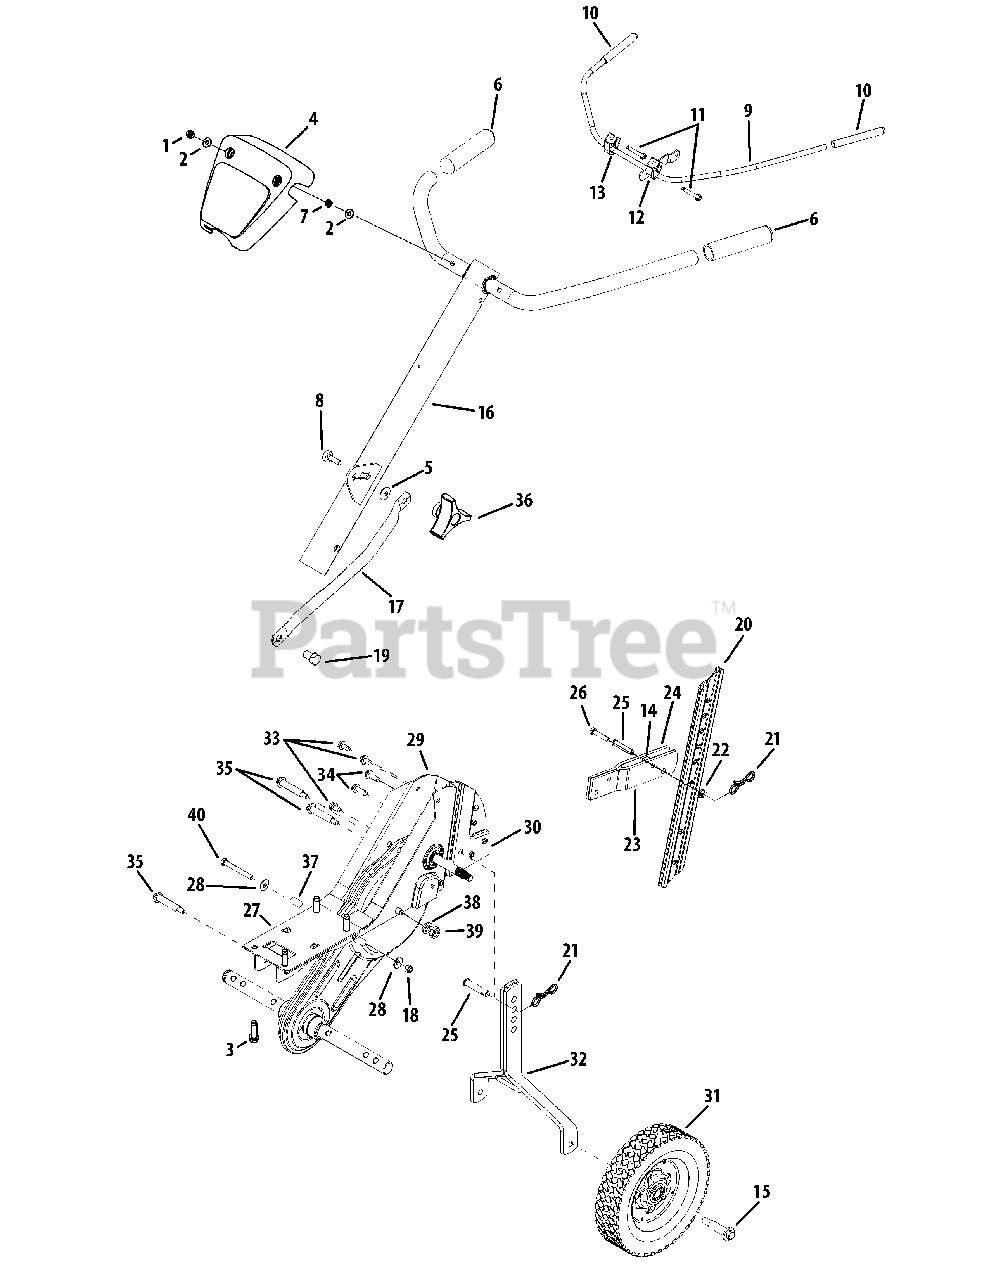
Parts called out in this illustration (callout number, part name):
1	Acorn Lock Nut, 1/4-20
2	Flat Washer, .271" x.630"
3	Screw, 3/8-16 x 1.250
4	Handle Cover
5	Bell Washer, .34"
6	Handle Grip
7	Jam Nut, 1/4-20
8	Carriage Bolt, 5/16-18 x 1
9	Clutch Handle Assembly
10	Clutch Grip
11	Hex Bolt, 1/4-20 x 2.25"
12	Clutch Handle Holder
13	Flat Washer, .385" x .62"
15	Shoulder Screw, .496 x 1.445
16	Handle Assembly Complete
17	Handle Brace
18	Nylon Hex Nut, 5/16-18
19	Hex Bolt, 1/2-20
21	Cotter Pin, Bow Tie
22	Hex Flange L-Nut, 5/16-18
23	Tail Piece Bracket, Left
24	Tail Piece Bracket, Right
25	Clevis Pin
26	Hex Bolt, 5/16-18 x 1.5"
28	Bell Washer, .340" x .872"
31	Wheel, 8 x 1.75
32	Wheel Hanger Bracket Assembly
33	Screw, Self-tapping, 5/16-18, .750,
34	Hex Washer TT-Tap Screw
35	Shoulder Bolt, 5/16-18
36	Hand Knob
38	Lock Washer, 7/16
39	Jam Nut, 7/16-20
40	Hex Bolt, 5/16-18 x 2.75"
